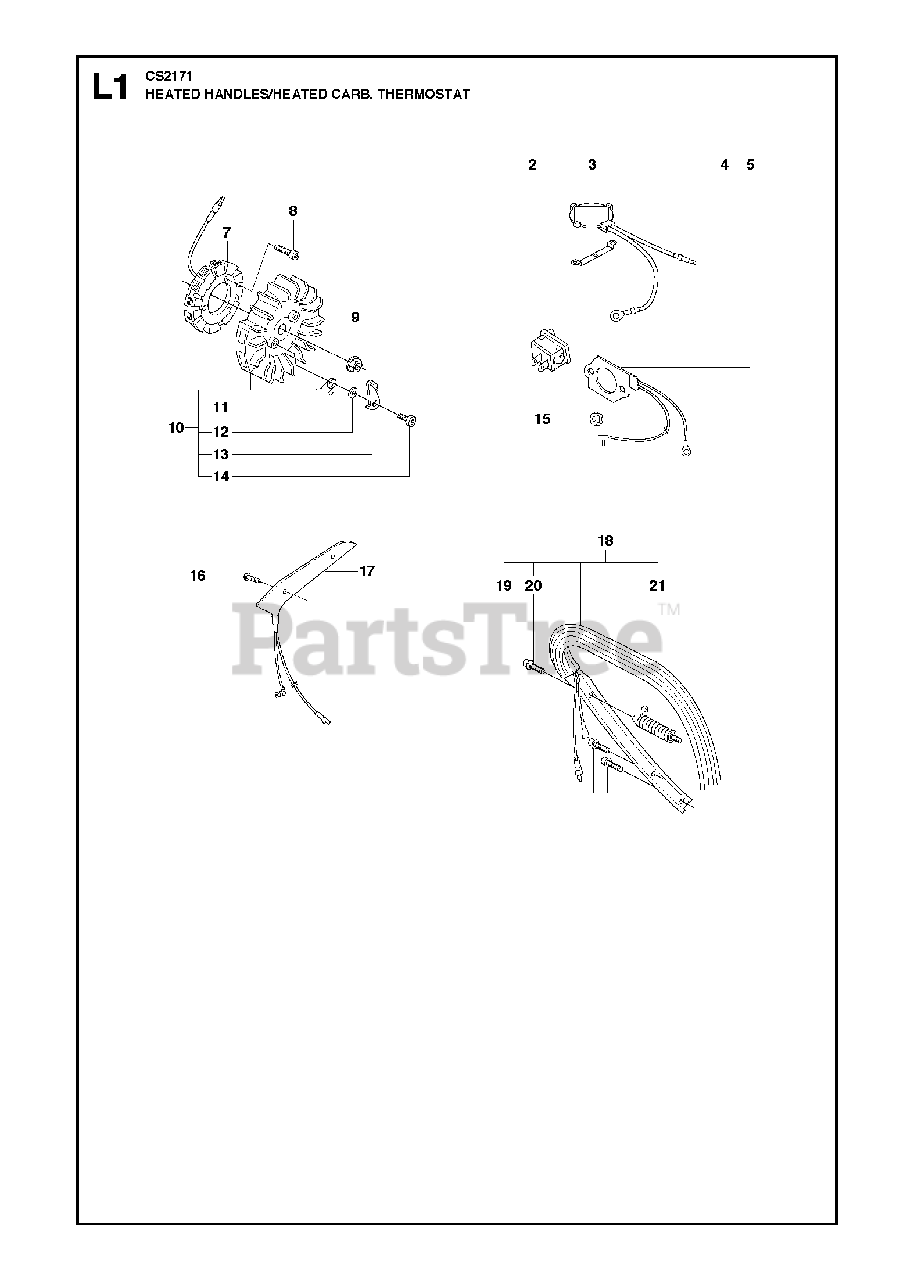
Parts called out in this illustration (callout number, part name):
3	THERMOSTAT
5	FOIL ELEMENT
7	GENERATOR
9	NUT W/ WASHER
11	SPRING
12	WASHER
13	PAWL
14	SCREW M5X14
17	PLATE (G)
18	FRONT HANDLE
19	SCREW
20	SCREW
21	ANTIVIBE MOUNT
